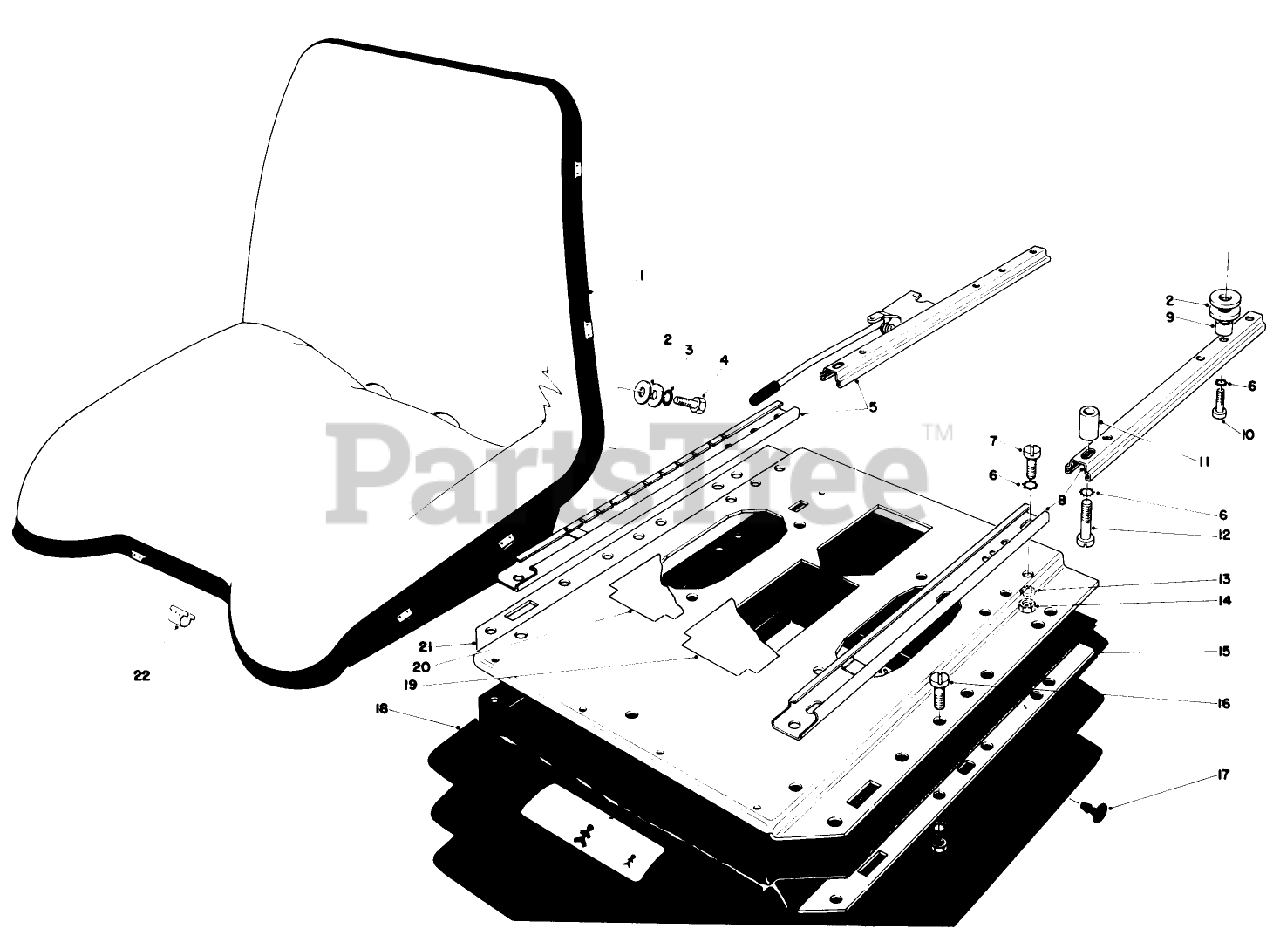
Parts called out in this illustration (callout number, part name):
1	BUCKET SEAT
2	13 MM WASHER
3	SERRATED WASHER
4	HEX HD CAPSCREW
5	ADJ TRACK & LATCH
6	SERRATED WASHER
7	Cylinder Bolt M8X16
8	ADJ TRACK
9	SLEEVE
10	CYL BOLT
11	SLEEVE
12	CYL BOLT
13	SPRING WASHER
14	Nut M8
16	CAPSCREW
17	PLUG-PLASTIC
18	BELLOWS
19	CENTER COVER
20	COVER
21	Upper Suspension Plate Complete
22	OUTSIDE CLAMP
